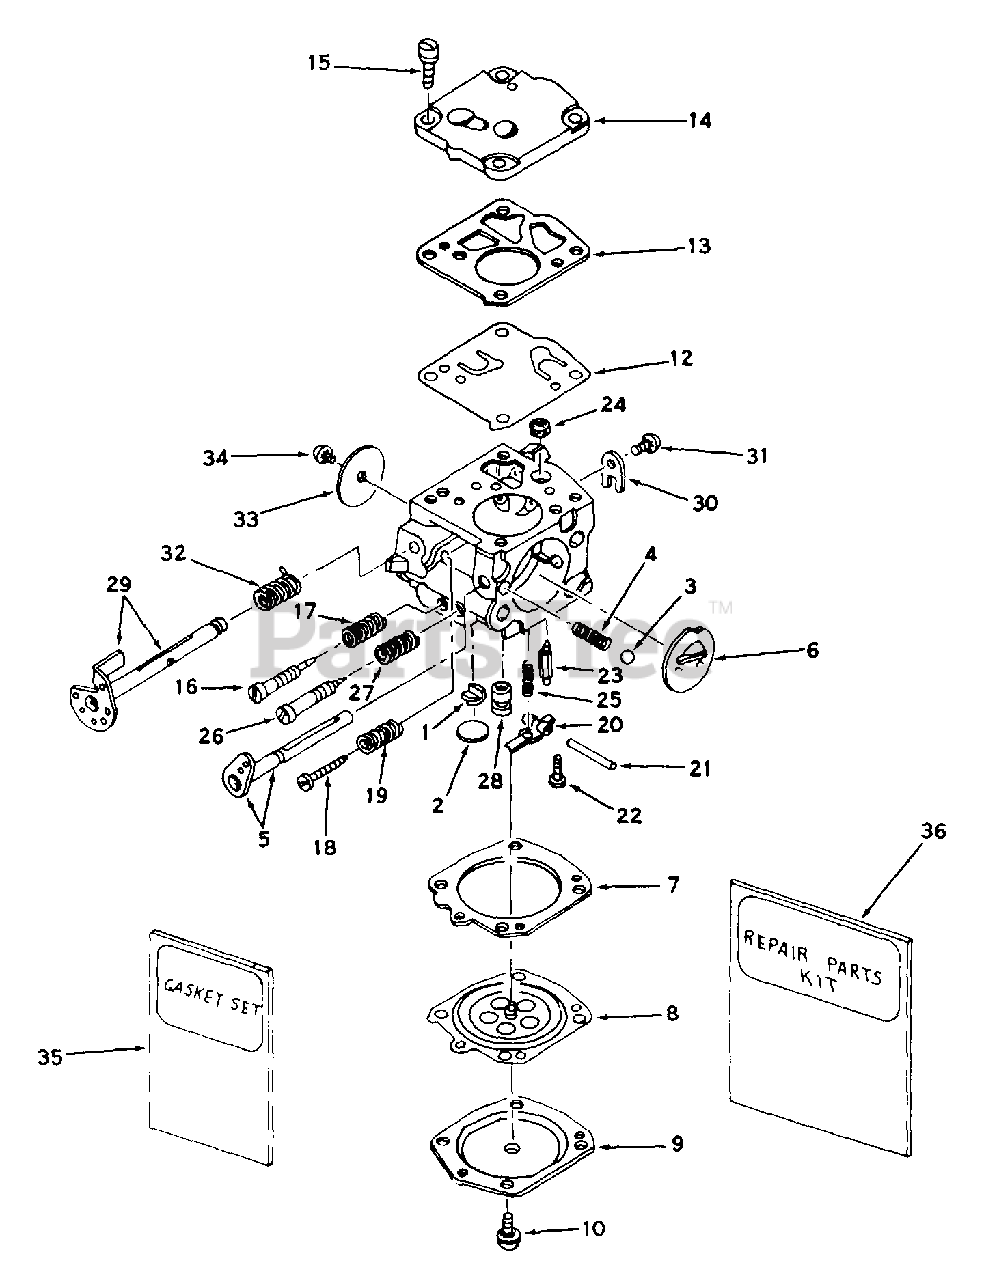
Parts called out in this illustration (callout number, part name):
1	"Reducer, Body channel
2	Plug, Welch
3	Ball, Choke friction
4	Spring, Choke friction
5	Shaft & Lever, Choke
6	Shutter, Choke
7	Gasket, Diaphragm
8	Diaphragm
9	Cover, Diaphragm
10	Screw, retaining
12	Diaphragm, Fuel pump
13	Gasket, Fuel pump
14	Cover, Fuel pump
15	Screw, Retaining
16	Screw, Idle mixture
17	Spring, Idle mixture screw
18	Screw, Idle speed
19	Spring, Idle speed screw
20	Lever, inlet control
21	Pin, Inlet pinion
22	Screw, Retaining
23	Needle, Inlet
24	Screen, Inlet
25	Spring, Inlet tension
26	Screw, High speed mixture
27	Spring, High speed mixture screw
28	Check Valve, Nozzle
29	Shaft & Lever, Throttle
30	Clip, Throttle shaft
31	Screw, Retaining
32	Spring, Throttle shaft retainer
33	Shutter, Throttle
34	Screw, Throttle shutter
35	Gasket Set
36	Repair Parts Kit
